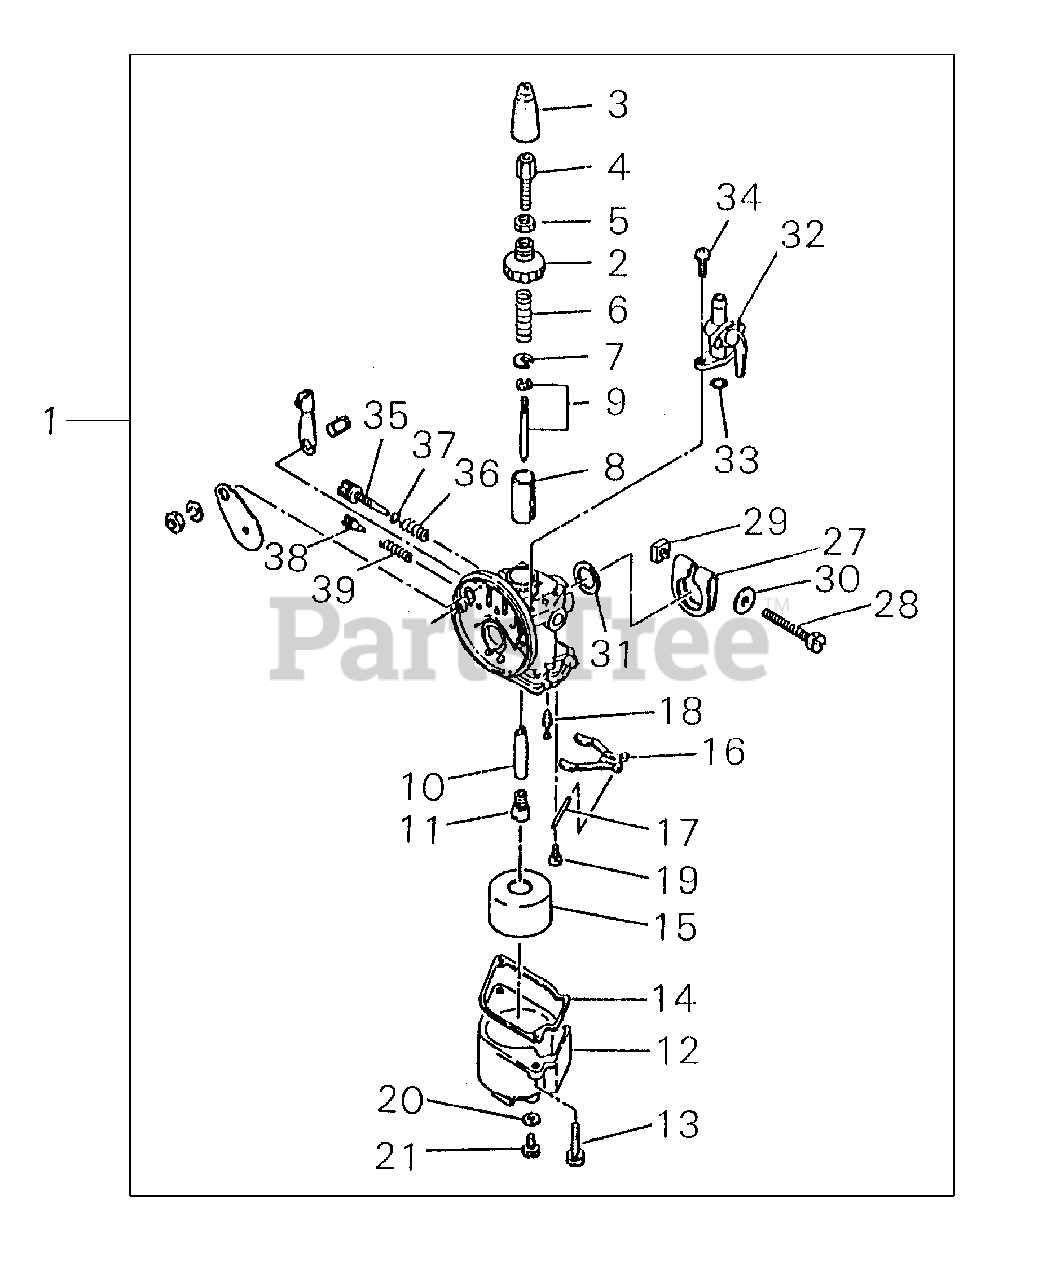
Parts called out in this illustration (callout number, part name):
1	CARBURETOR
2	CAP, CARBURETOR
3	GROMMET
4	NUT, CABLE ADJUST
5	LOCKNUT
6	SPRING, THROTTLE
7	RETAINER
8	VALVE, THROTTLE
9	JET, NEEDLE
10	NOZZLE
11	JET, MAIN
12	CHAMBER, FLOAT
14	GASKET
15	FLOAT
16	HINGE, FLOAT
17	PIN, HINGE
18	VALVE, INLET NEEDLE
19	SCREW
20	WASHER
21	SCREW, DRAIN
27	CLAMP
28	BOLT
30	WASHER
31	SEAL
32	COCK, FUEL
33	O-RING
34	SCREW
35	SCREW, SLOW STOP
36	SPRING
37	O-RING
38	SCREW, SLOW AIR
39	SPRING
